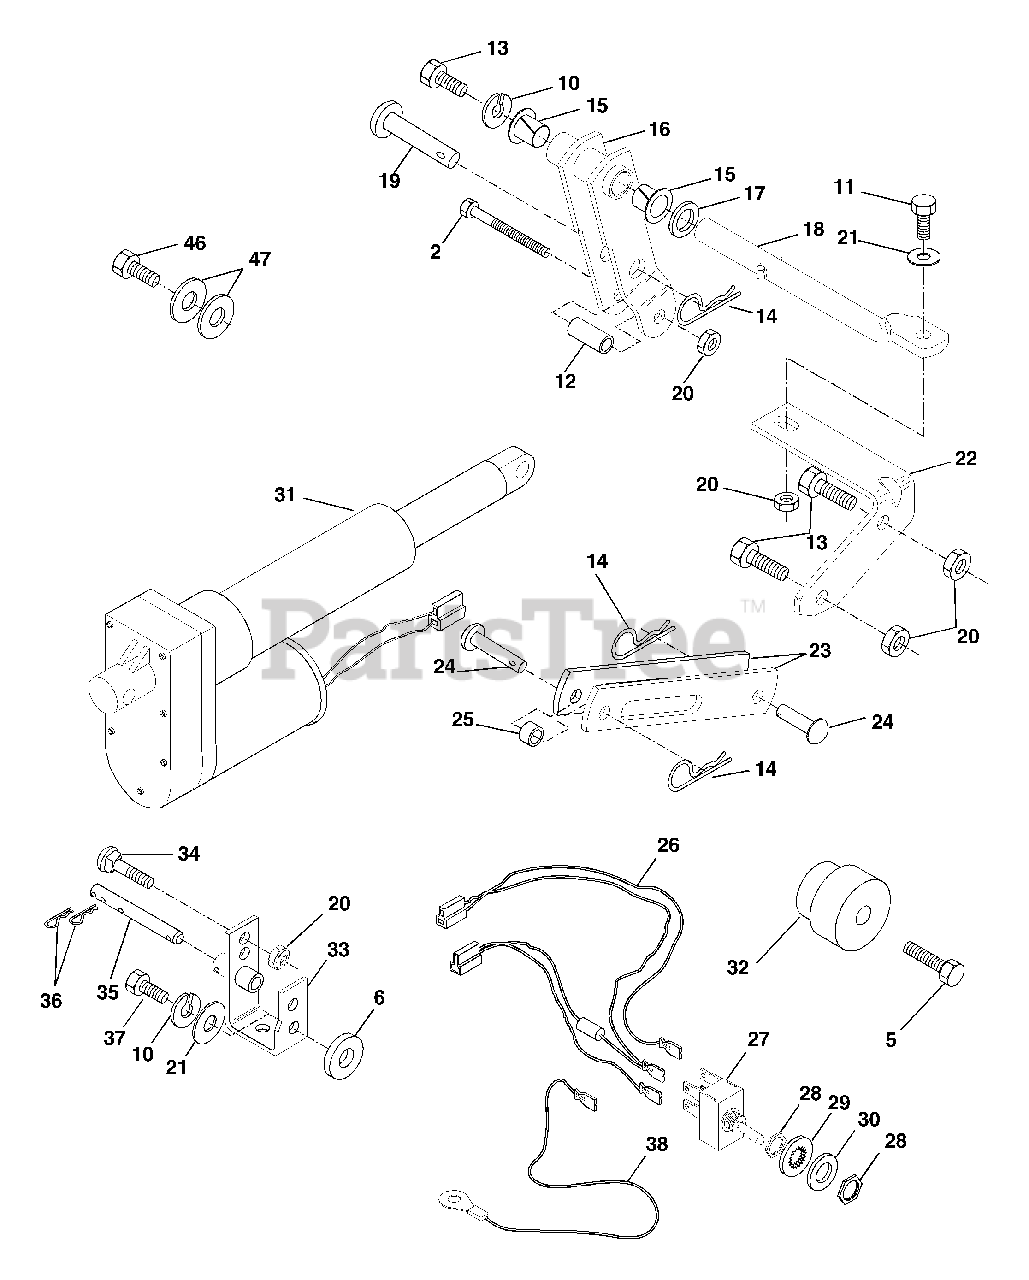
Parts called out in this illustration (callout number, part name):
2	Bolt, Hex 3/8-16 x 2-1/4 Grade 5
5	Bolt, Hex 3/8-16 x 1-3/8
6	Washer 13/32 x 7/8 x 7 Ga.
10	Washer, Lock
11	Bolt, Hex 3/8-16 x 1-1/4
12	Bushing .384 x 1/2 x 1-1/4
13	Bolt, Hex 3/8-16 x 7/8
14	Spring, Retainer
15	Nyliner
16	Arm, Pivot
17	Washer 21/32 x 1 x 21 Ga.
18	Rod, Pivot Support
19	Pin, Pivot
20	Locknut 3/8-16
21	Washer 13/32 x 7/8 x 16 Ga.
22	Bracket, Pivot Rod
23	Link, Lift
24	Pin, Pivot
25	Spacer
26	Harness, Lift Kit
27	Switch, Lift
28	Nut, Switch
29	Washer, Lock Int. Tooth
30	Washer 15/32 x 3/4 x 16 Ga.
31	Electric, Actuator
32A	Hub, Lever Lift (Splined)
32B	Hub, Lever Lift (Tapered)
33	Bracket Asm, Actuator, Gear Drive
34	Bolt, Carriage 3/8-16 x 1
35	Pin, Actuator
36	Spring, Retainer
37	Bolt, Hex 3/8-16 x 1
38	Wire, Ground
46	Screw 5/16-18 x 1-1/4
47	Washer 11/32 x 1-1/2 x 10 Ga.
